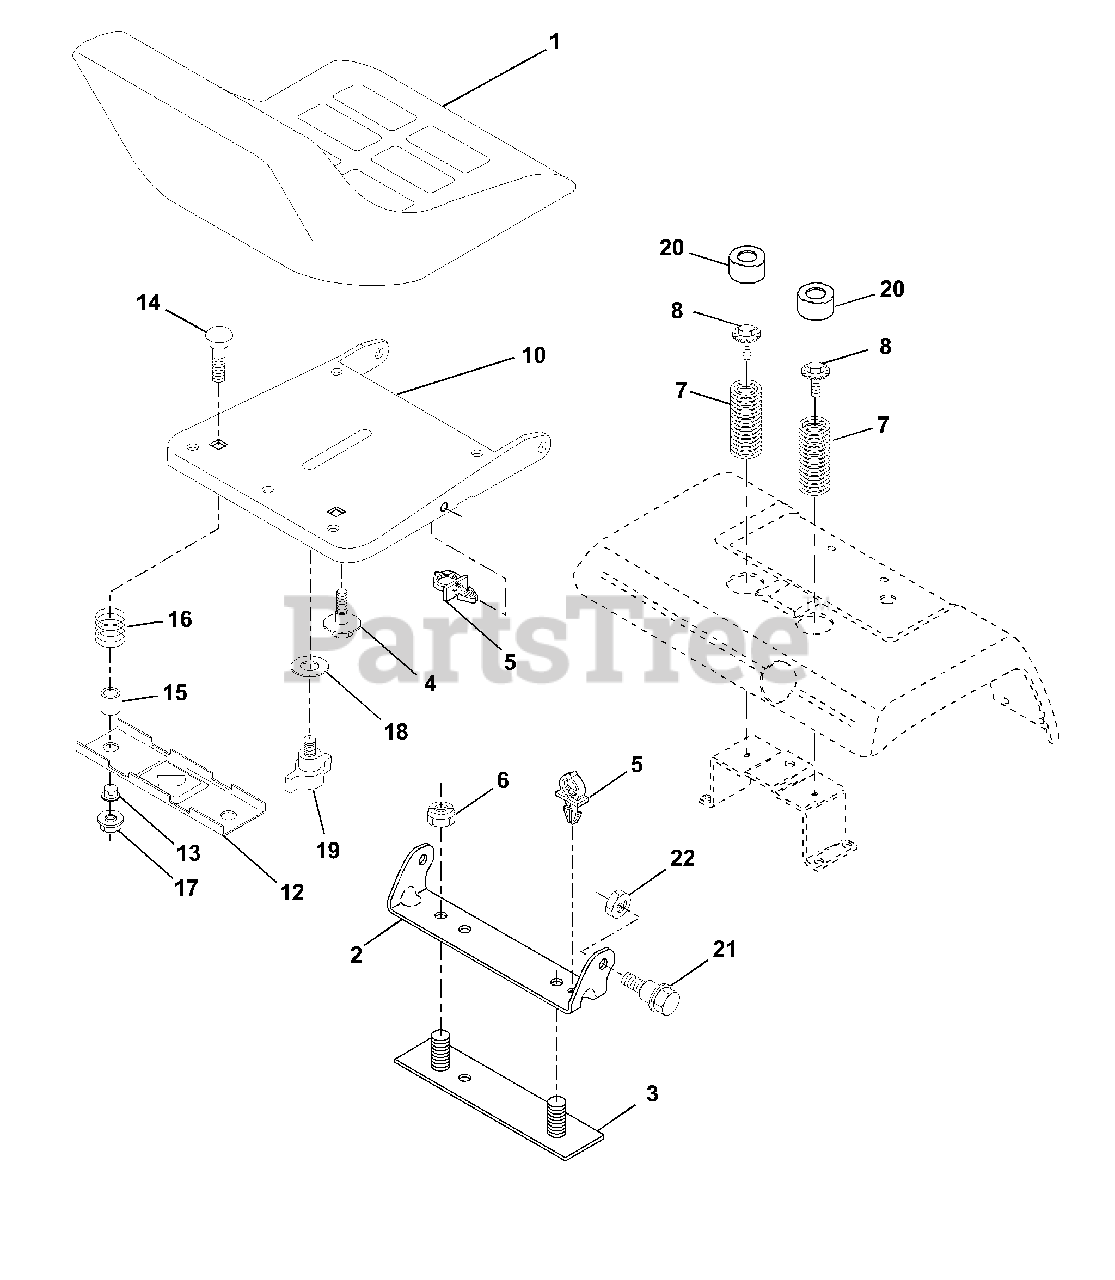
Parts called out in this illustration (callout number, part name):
1	Seat
2	Bracket, Pivot Seat
3	Strap, Fender Asm.
4	Bolt, Shoulder 5/16-18 x .62
5	Clip, Push-In Hinged
6	Nut, Lock Hex w/Ins. 3/8-16 Unc
7	Spring, Seat Cprsn.
8	Bolt 5/16-18 UNC x 3/4 w/Sems
10	Pan, Seat
12	Bracket, Mounting Switch
13	Bushing, Snap
14	Bolt, Carriage 1/4-20 x 1-1/2
15	Spacer, Split
16	Spring, Cprsn.
17	Nut, Lock 1/4 Lg. Flg. Gr. 5
18	Washer 17/32 x 1-3/16 x 12 Ga.
19	Knob, Seat
20	Cap, Spring Seat Blk
21	Bolt 5/16-18 Unc-2A
22	Nut, Crownlock 5/16-18
